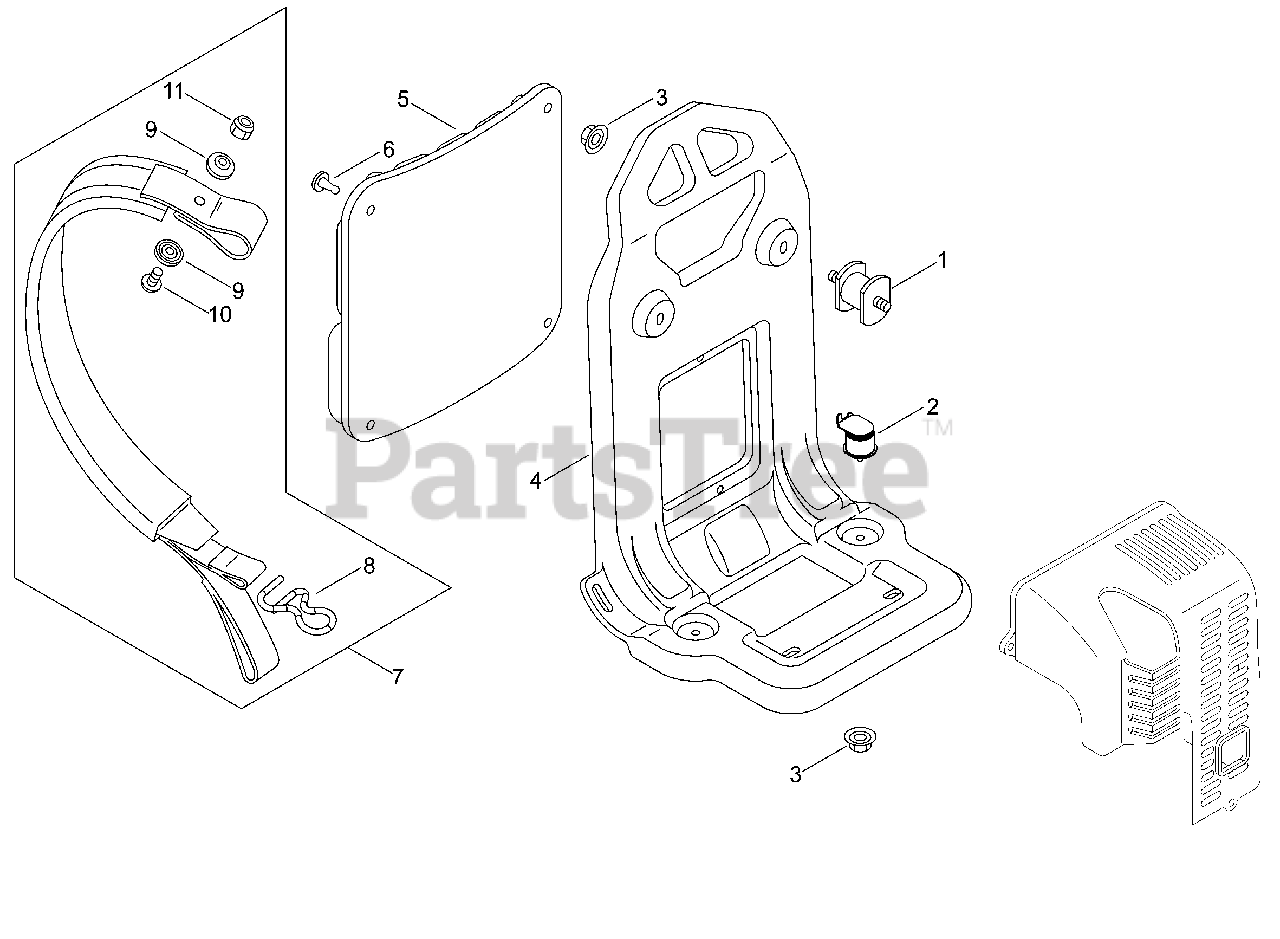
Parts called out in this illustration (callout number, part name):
1	CUSHION 6
2	CUSHION 6
4	FRAME, BACKPACK
5	CUSHION, BACKPACK
7	HARNESS ASSY, BACKPACK
8	+RING, HARNESS
9	+WASHER 5.2×22×2.0
10	+SCREW 5×16
11	+NUT, LOCK M5
